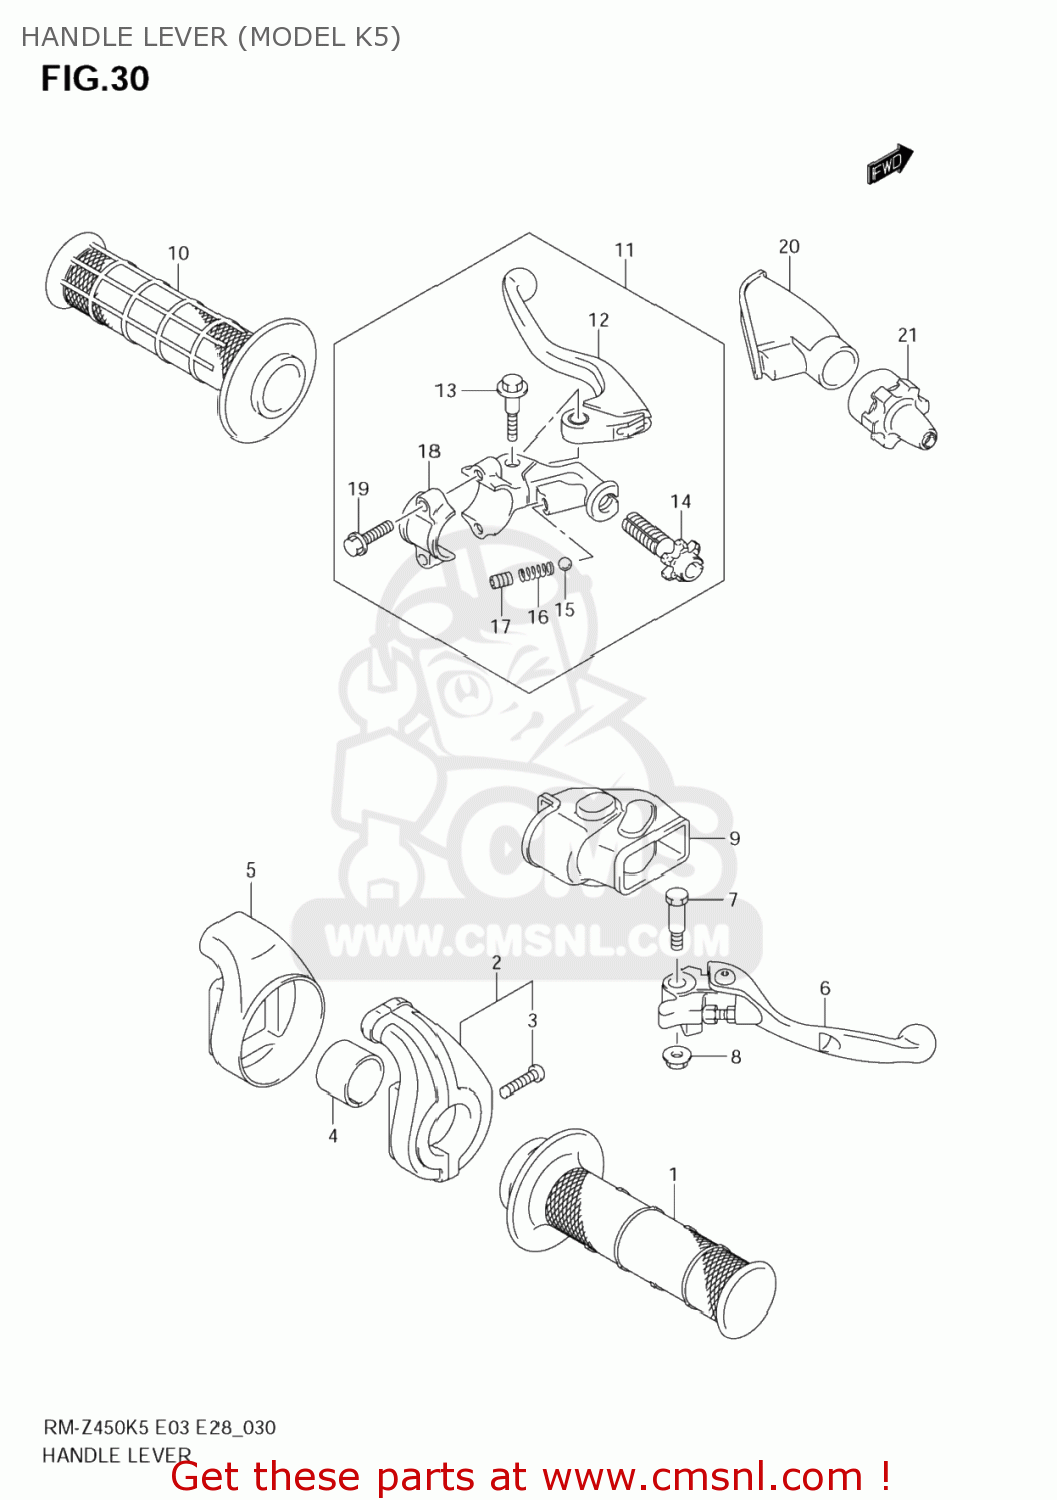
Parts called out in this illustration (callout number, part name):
1	GRIP,THROTTLE
2	CASE ASSY,THROTTLE
3	SCREW,CASE
4	COLLAR,THROTTLE CASE
5	COVER,THROTTLE CASE
6	LEVER ASSY,BRAKE
7	BOLT,BRAKE LEVER
8	NUT
9	COVER,BRAKE LEVER
10	GRIP,L
11	LEVER ASSY,CLUTCH
12	LEVER,CLUTCH
13	BOLT
14	ADJUSTER,CLUTCH CABLE
15	BALL
16	SPRING
17	SCREW(6X8)
18	BRACKET,CLUTCH LEVER HOLDER
19	BOLT, BRACKET
20	COVER,CLUTCH LEVER
21	COVER,CLUTCH ADJUSTER
